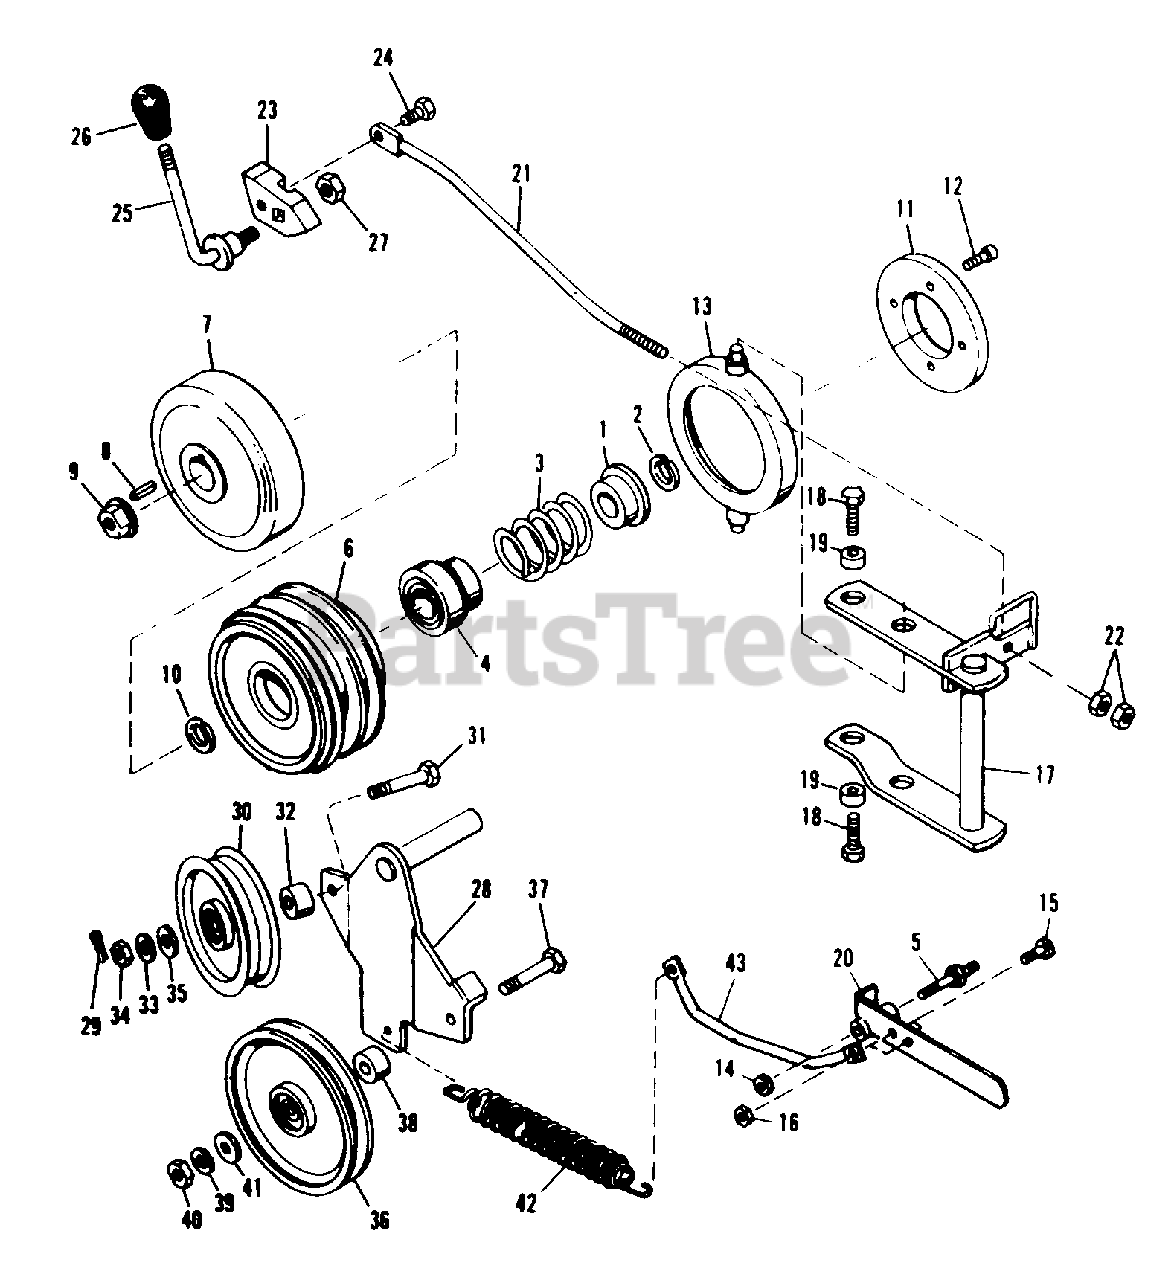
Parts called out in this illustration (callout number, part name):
1	Inner Spring Guide
2	Ring, Retaining
4	Bushing Assembly
7	Clutch Plate Assy.
9	Washer Base Lock Nuts
10	Ring, Retaining
12	Socket Hd. Screw, 1/4"-20 x 5/8"
13	Support Brake Assy.
14	Hex Lock Nut, Full, 7/16"-14
15	Hex Cap Screw, 5/16"-18 x 3/4"
16	Hex Lock Nut, Full, 5/16"-18
17	Pivot Assy.
18	Thread Forming Screw, 5/16" x 18 x 1" lg.
20	Handle Assy.
21	Control Rod
22	Hex Nut Full, 5/16"-18
24	Special Cap Screw, 5/16"-UNC-2A x 7/8" Grade 5
25	Handle, Clutch PTO
26	Knob
27	Hex Lock Nut, Full, 3/8"-16
28	Pivot Arm Assy.
29	Cotter Pin, 3/16" x 1-1/2"
31	Hex Cap Screw, 3/8"-16 x 2"
33	Lock Washer, 3/8"
34	Hex Nut, Full, 3/8"-16
35	Plain Washer, 5/16"
36	Idler Pulley
37	Hex Cap Screw, 3/8"-16 x 2"
39	Lock Washer, 3/8"
40	Hex Nut, Full, 3/8"-16
41	Plain Washer, 5/16"
42	Spring Tension
43	Spring Tension Rod
